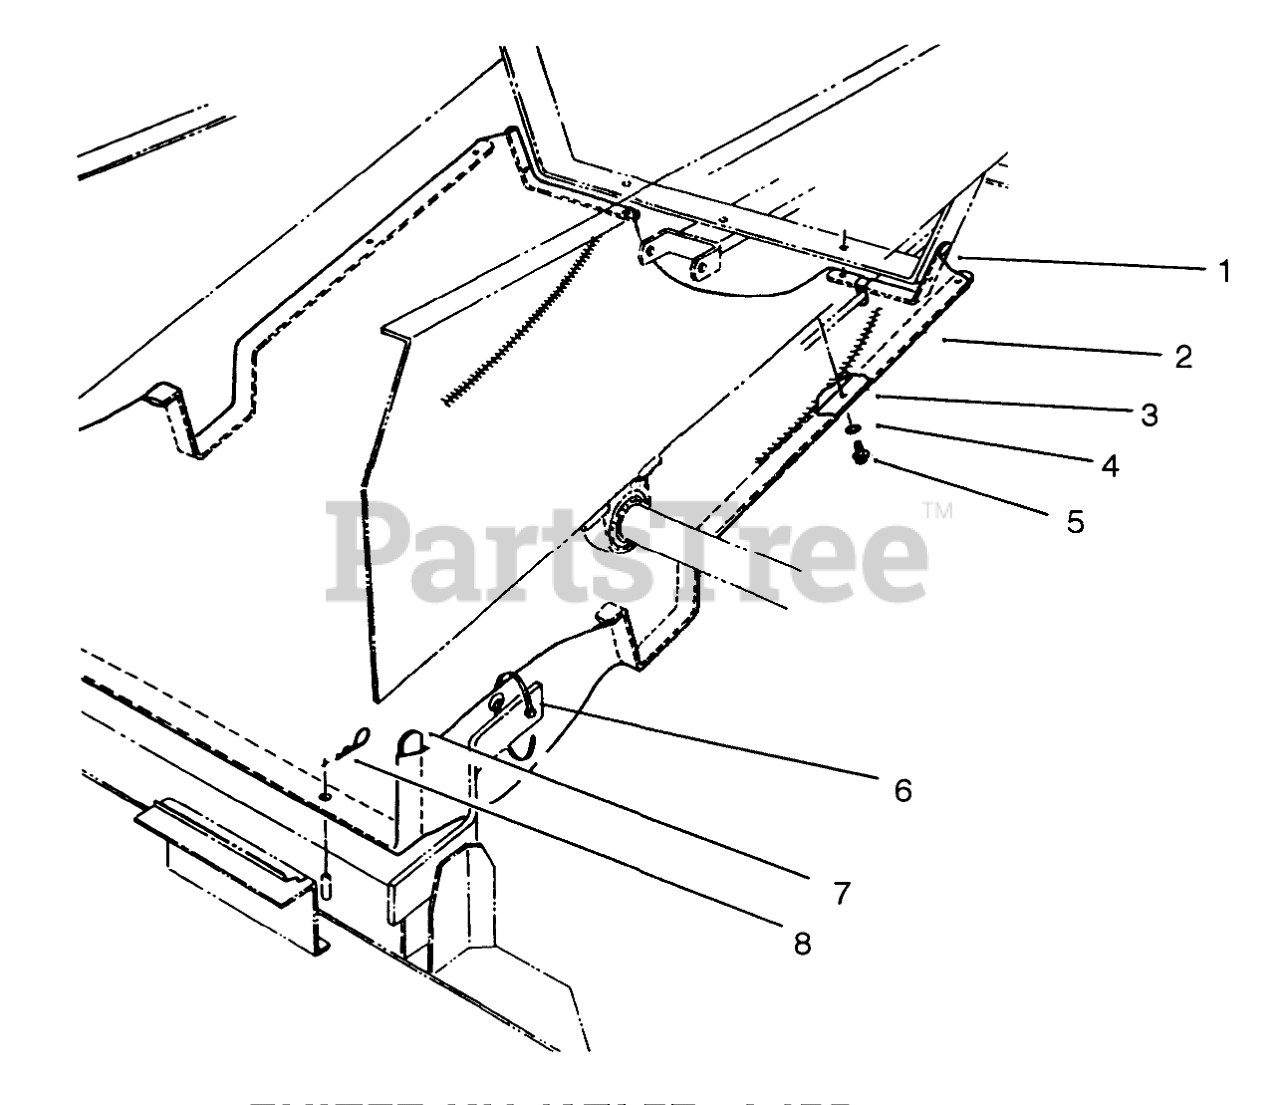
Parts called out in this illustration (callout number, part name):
1	SHIELD BRACKET R
2	CLOTH SHIELD
3	Support-Side
4	WASHER-LOCK
5	SCREW-HWH
6	TIE-CABLE
7	DECK SHIELD SUPPORT R
8	PIN-HAIR
